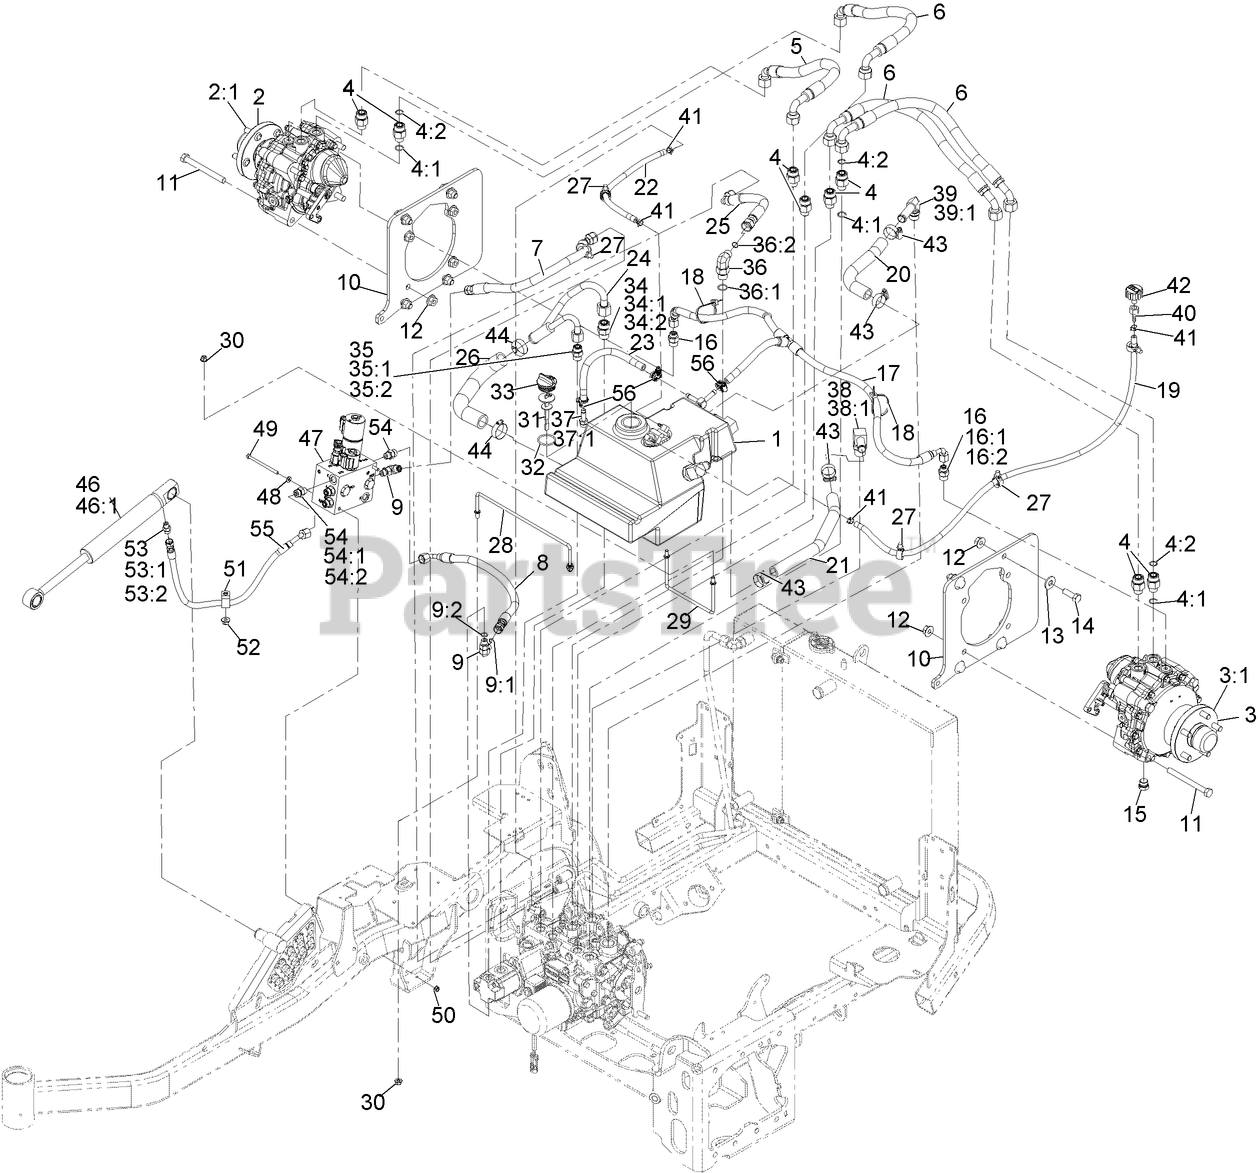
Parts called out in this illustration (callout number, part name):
1	HYD RESERVOIR ASM
2	MOTOR-HYD, RH
2:1	5 STUD WHEEL HUB KIT
3	MOTOR-HYD, LH
3:1	5 STUD WHEEL HUB KIT
4	FITTING-STRAIGHT
4:1	O-RING
4:2	O-RING
5	HOSE ASM
6	HOSE ASM
7	HOSE ASM
8	HOSE ASM
9	FITTING-ELBOW, 90 DEG
9:1	O-RING
9:2	O-RING
10	PLATE-MOTOR
11	SCREW-HH
12	NUT-HHF
13	WASHER-SPRING
14	SCREW-HH
15	PLUG-MAGNETIC
16	FITTING-STRAIGHT
16:1	O-RING
16:2	O-RING
17	TEE HOSE ASM
18	TIE-CABLE
20	HOSE-RETURN
21	HOSE-RETURN
24	TUBE ASM
25	HOSE ASM
26	HOSE-SUCTION
27	CLIP-TIE
28	ROD-SUPPORT, HYD TANK
29	ROD-SUPPORT, HYD TANK
30	NUT-HF, NI
31	DIPSTICK
32	O-RING
33	PLUG-PLASTIC
34	FITTING-STRAIGHT
34:1	O-RING
34:2	O-RING
35	FITTING-STRAIGHT
35:1	O-RING
35:2	O-RING
36	FITTING-ELBOW, 90 DEG
36:1	O-RING
36:2	O-RING
37	ADAPTER-STRAIGHT
37:1	O-RING
38	FITTING-ELBOW, 90
38:1	O-RING
39	FITTING-90
39:1	O-RING
40	FITTING-STRAIGHT
41	CLAMP-HOSE
42	BREATHER
43	CLAMP-HOSE
44	CLAMP-HOSE
46	CYLINDER-LIFT
46:1	KIT, CYL REPAIR
47	VALVE ASM-LIFT AND FOLD
48	WASHER-FLAT
49	SCREW-HH
50	NUT-HF
51	CLIP-LOOM
52	NUT-HF, NI
53	FITTING-HYD, STRAIGHT
53:1	O-RING
53:2	O-RING
54	FITTING-STRAIGHT
54:1	O-RING
54:2	O-RING
55	HOSE ASM
56	CLAMP-HOSE
